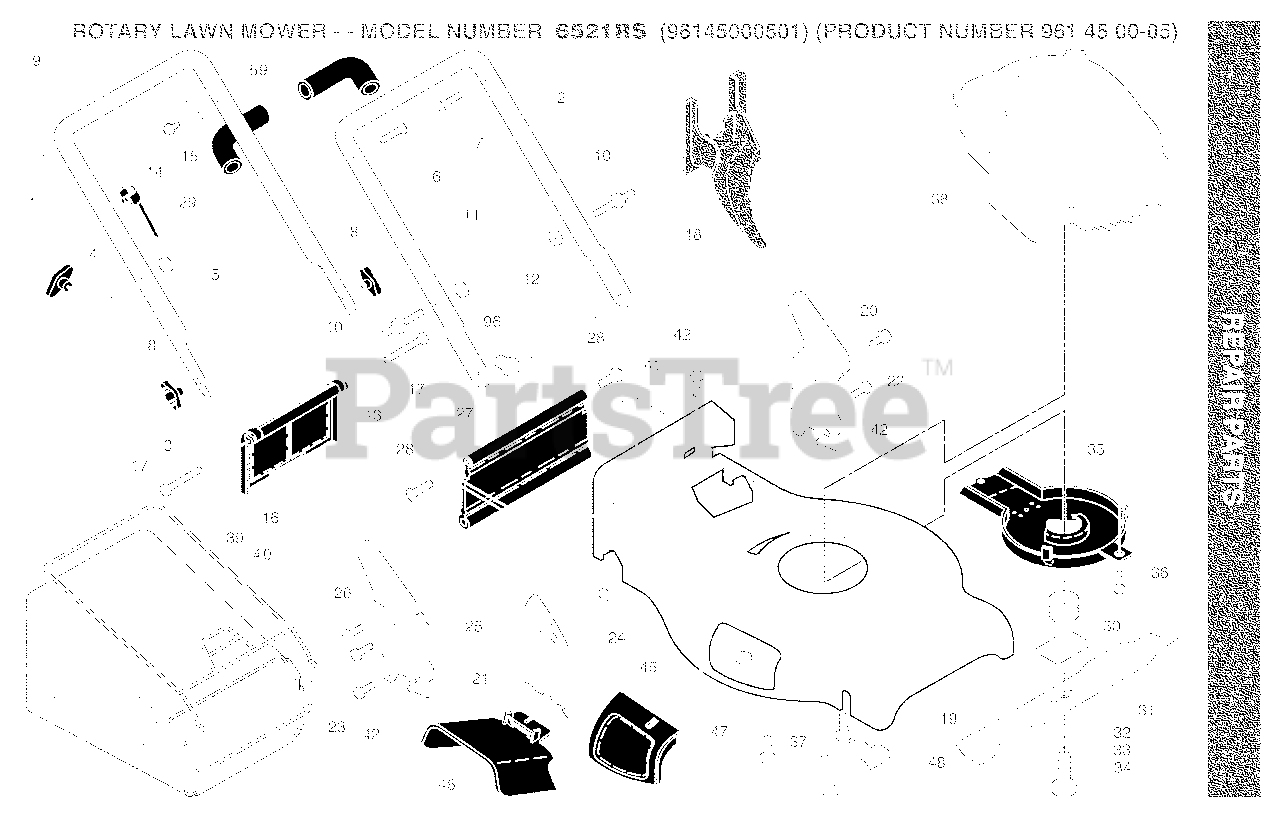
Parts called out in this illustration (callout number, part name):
1	Handle, Upper
2	Handle, Lower
3	Spring, Rear Door, RH
4	Guide, Rope, Side
5	Nut, Hex Lockwasher Insert 1/4-20
6	Wire, Tie
7	Bolt, Handle 5/16-18 x 1.75
8	Knob, Handle
9	Bail, Flat, Auto-Walk, Orange
10	Bolt, Carriage
11	Nut, Hex, Centerlock 5/16-18 UNC
12	Cotter, Hairpin
13	Spring, Rear Door, LH
15	Bracket, Upstop
16	Rear Door Assembly
17	Bolt, Rear Door
18	Plug, Mulcher
19	Kit, Housing
20	Handle Bracket Assembly, LH
21	Handle Bracket Assembly, RH
22	Screw, Hex Washer Head
23	Bolt, Hex Head 5/16-18 x 5/8
24	Nut, Hex, with Lock Washer Insert 5/16-18
25	Baffl e, Side
26	Screw, Hi-Lo Thread #12 x 5/8
27	Skirt, Rear
28	Screw, Hinge 1/4-20 x 1.25
29	Cable, Operator Presence
30	Blade Adapter / Pulley
31	Blade, 21"
32	Washer, Hardened
33	Lockwasher, Helical Spring 3/8
34	Screw, Hex Head 3/8-24 x 1.38
35	Debris Shield
37	Bolt, Engine
39	Grassbag
40	Frame, Grassbag
41	Danger Decal
45	Mulcher Door Assembly
46	Defl ector, Discharge
48	Mounting Bracket, Debris Shield
59	Grip, Handle, Foam, Smooth
96	Clip, Cable
